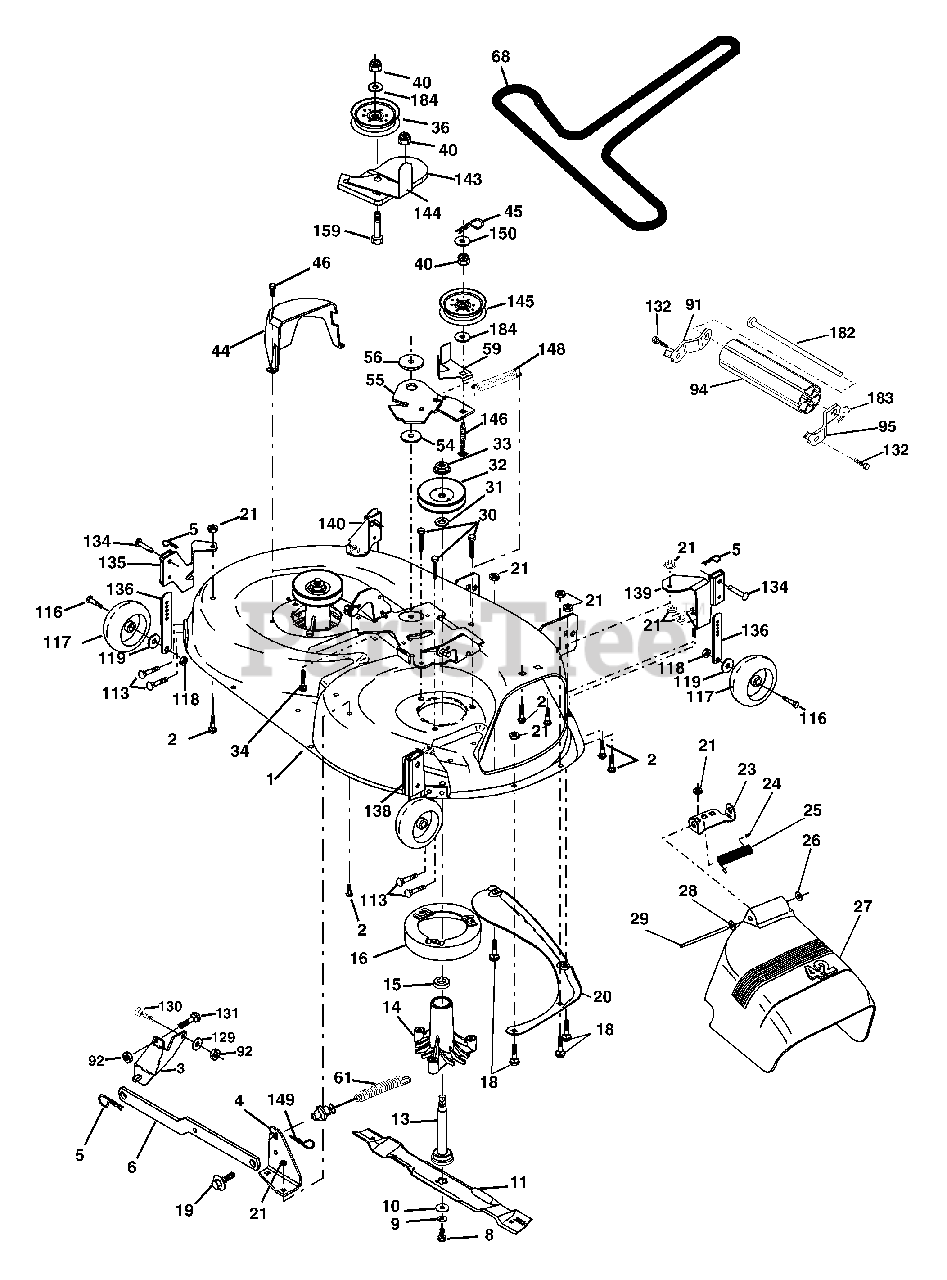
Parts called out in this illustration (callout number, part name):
1	Mower Deck Assembly, 42"
2	Bolt
3	Bracket Assembly,Sway Bar, Front
4	Bracket Sway Bar 42" Deck
5	Retainer Spring
6	Bar Sway Deck
8	Bolt, Hex 3/8-24 x 1.25 Gr. 8
9	Washer, Lock
10	Washer, Hardened
11	Blade Mower 42" High Perf.
13	Shaft Assembly, Mandrel, Vented
14	Housing, Mandrel, Vented
15	Bearing, Ball, Mandrel
18	Bolt, Carriage 5/16-18 x 5/8
19	Bolt, Shoulder
20	Baffle, Vortex
21	Nut Crownlock 5/16-18 unc
23	Bracket, Deflector
24	Cap, Sleeve
25	Spring, Torsion, Deflector
27	Shield, Deflector
28	Washer 11/32 x 5/8 x 16 Ga.
29	Rod, Hinge
30	Screw Thdrol Hex
31	Washer, Spacer
32	Pulley, Mandrel
33	Nut, Toplock, Flanged
34	Bolt Carr. Sh 3/8-16 x 1-1/2 Gr. 5
36	Pulley, Idler, Flat
40	Nut Lock Flg 3/8-16 unc
44	Guard, Mandrel, L.H.
45	Retainer
46	Screw, Thd. Roll 1/4-20 x 5/8
54	Washer, Hardened
55	Arm, Idler
56	Spacer, Retainer
59	Guard, TUV Idler
61	Spring Ext Elect Clutch 42" Dck
91	Bracket Asm Noseroller Lh
92	Nut Lock Hex w/Ins. 3/8
94	Roller Nose 38"-50"
95	Bracket Asm Noseroller Rh
113	Screw 5/16-18 x 3/4 Tap R
116	Bolt, Shoulder
117	Wheel, Gauge
118	Nut, Centerlock 3/8-16
119	Washer 3/8 x 7/8 x 14 Ga.
129	Washer 13/32 x 13/16 x Ga.
130	Bolt Fin Hex 3/8-16 unc x 1 Gr. 5
131	Bolt Rdhd Sqnk 3/8-16 unc x 1
132	Screw 3/8-16 x .75
134	Pin Head Rivet
135	Bracket Asm Whl GA R LH
136	Bar Adjusting GA WHL
138	Bracket Asm Whl GA R RH
139	Bracket Asm Whl GA F RH
140	Bracket Asm Whl GA F LH
143	Bracket Arm Idler 42"
144	Keeper Belt 42" Clutch Cable
145	Pulley Idler Flat
146	Bolt Carriage Idler
148	Spring Return Idler
149	Retainer Spring Yellow Zinc
150	Washer 9/32 x 3/4 x 10 Ga.
159	Bolt Rdhd Sqn 3/8-16 unc x 1- 3/4
182	Rod Roller Nose
183	Retainer Spring
184	Washer 13/32 x 7/8 x 10 Ga.
